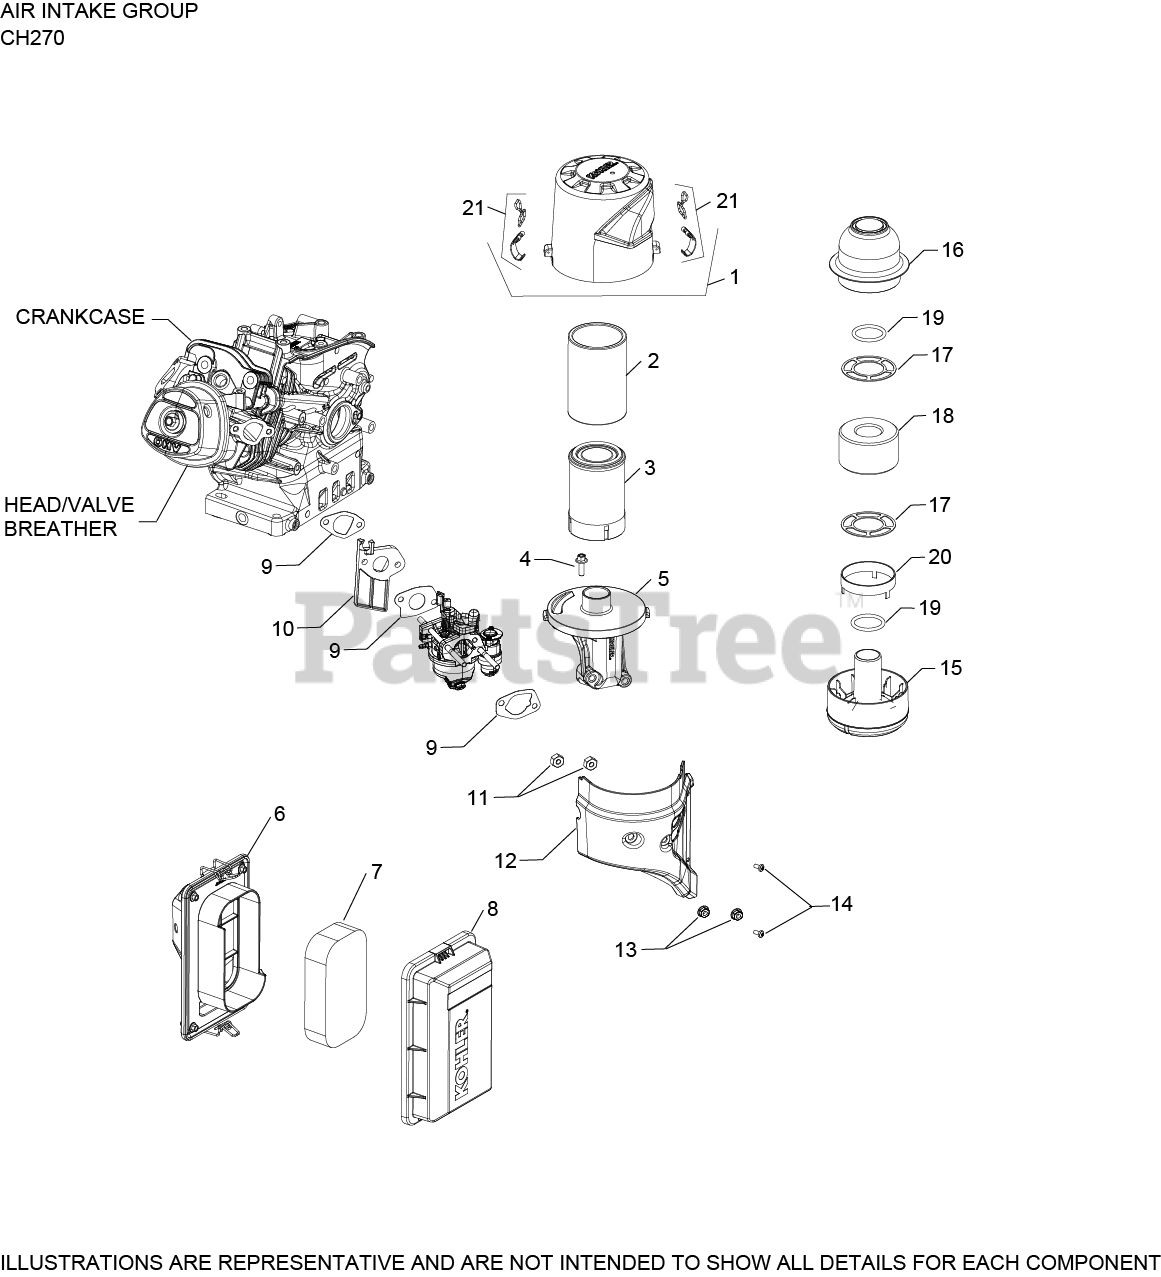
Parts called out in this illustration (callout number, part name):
1	COVER, AIR CLEANER ASSEMBLY
2	ELEMENT, PRE-CLEANER
3	ELEMENT, AIR FILTER - Also available Retail Packaged 17 883 07-S1 Air Filter Kit
4	SCREW, M6 X18
5	KIT, AIR CLEANER BASE ASSEMBLY
9	KIT, INTAKE GASKET
10	KIT, CARBURETOR INSULATOR
11	NUT, HEX (M6 THREAD, M8 BODY)
12	COVER, AIR CLEANER BASE SHIELD
13	NUT, HEX FLANGE LOCK (M6)
14	SCREW,COVR TO BLWR HOUSING
21	KIT, LATCH CLIP
